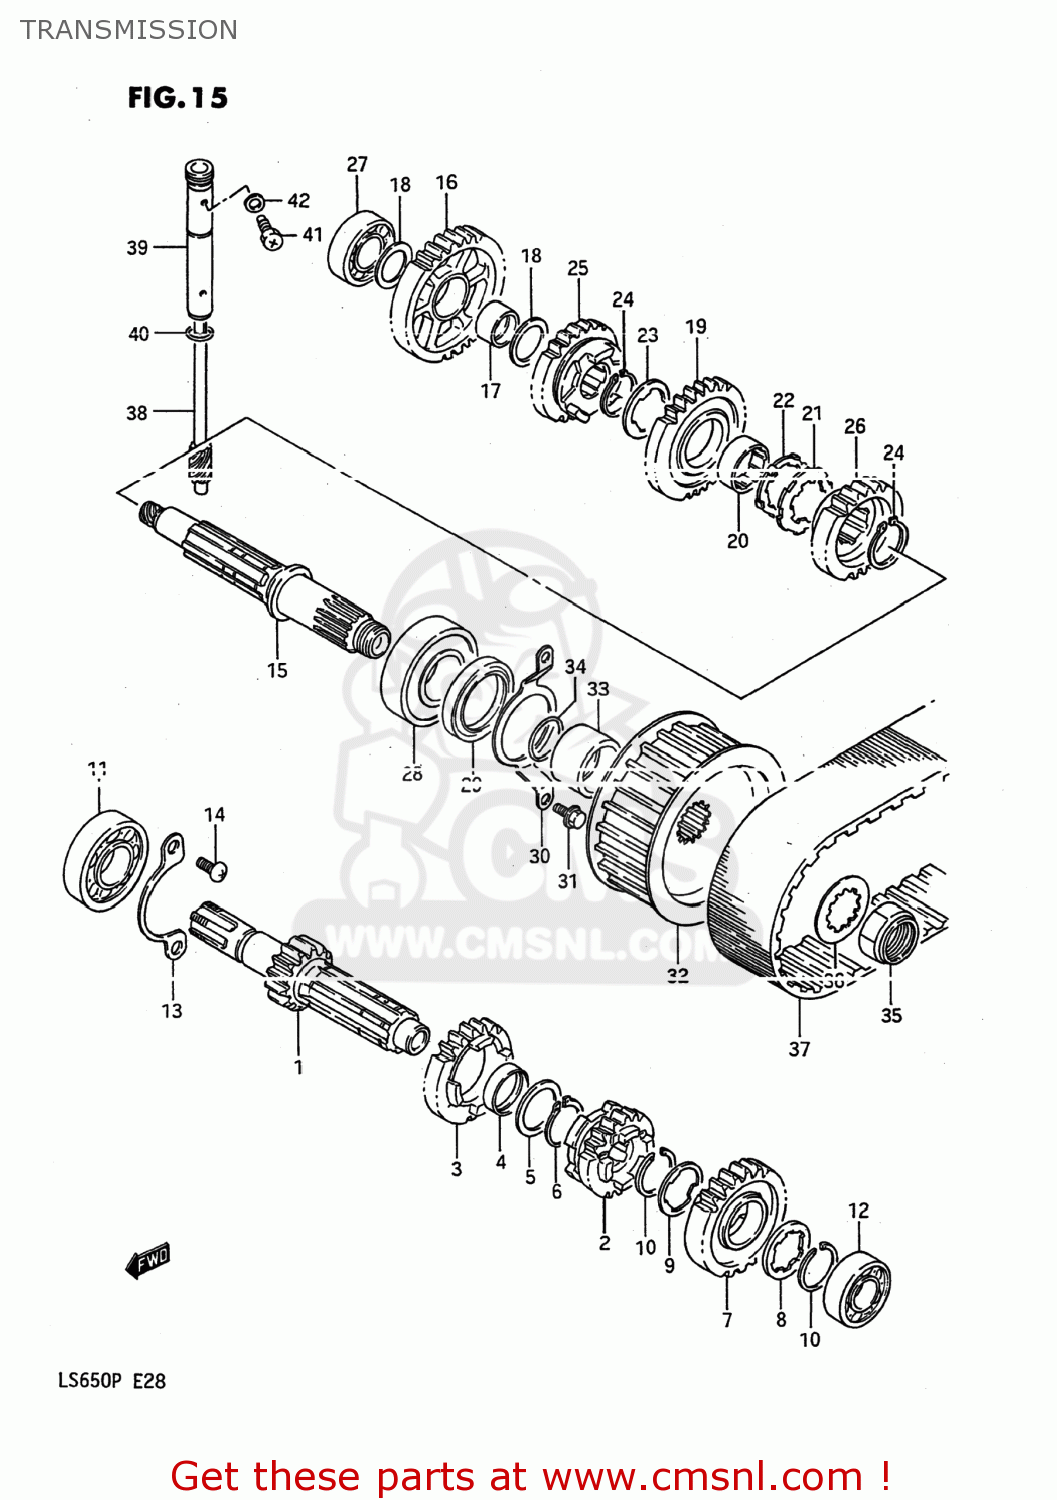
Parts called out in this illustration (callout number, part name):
1	COUNTER SHAFT
2	GEAR,SECOND DRIVE
3	GEAR,THIRD DRIVE
4	BUSH(25X29X8)
5	WASHER
6	RING,SNAP
7	GEAR,FOURTH DRIVE
8	WASHER
9	WASHER,LOCK
10	CIRCLIP
11	BEARING
12	BEARING(17X40X12)
13	RETAINER,CNTR SHAFT BEARING
14	SCREW
15	SHAFT,DRIVE
16	GEAR,1ST DRIVEN
17	BUSH(20X24X13)
18	WASHER
19	GEAR,SECOND DRIVEN
20	BUSHING
21	WASHER
22	WASHER,LOCK
23	WASHER,LOCK
24	RING,SNAP
25	GEAR,THIRD DRIVEN
26	GEAR,FOURTH DRIVEN
27	BALL BEARING 20X42X12
28	BALL BEARING 25X62X17
29	SEAL,OIL(36X50X6)
30	RETAINER,DRIVE SHAFT OIL SEAL
31	BOLT
32	PULLEY,FR
33	SPACER,FR PULLEY
34	O-RING
35	NUT
36	WASHER
37	BELT,DRIVE
38	GEAR,SPEEDOMETER DRIVEN
39	SLEEVE,TACHOMETER DRIVEN GEAR
40	O RING(D:1.3,ID:9.6)
41	BOLT
42	GASKET(6.2X11X1).2 (NAS)
